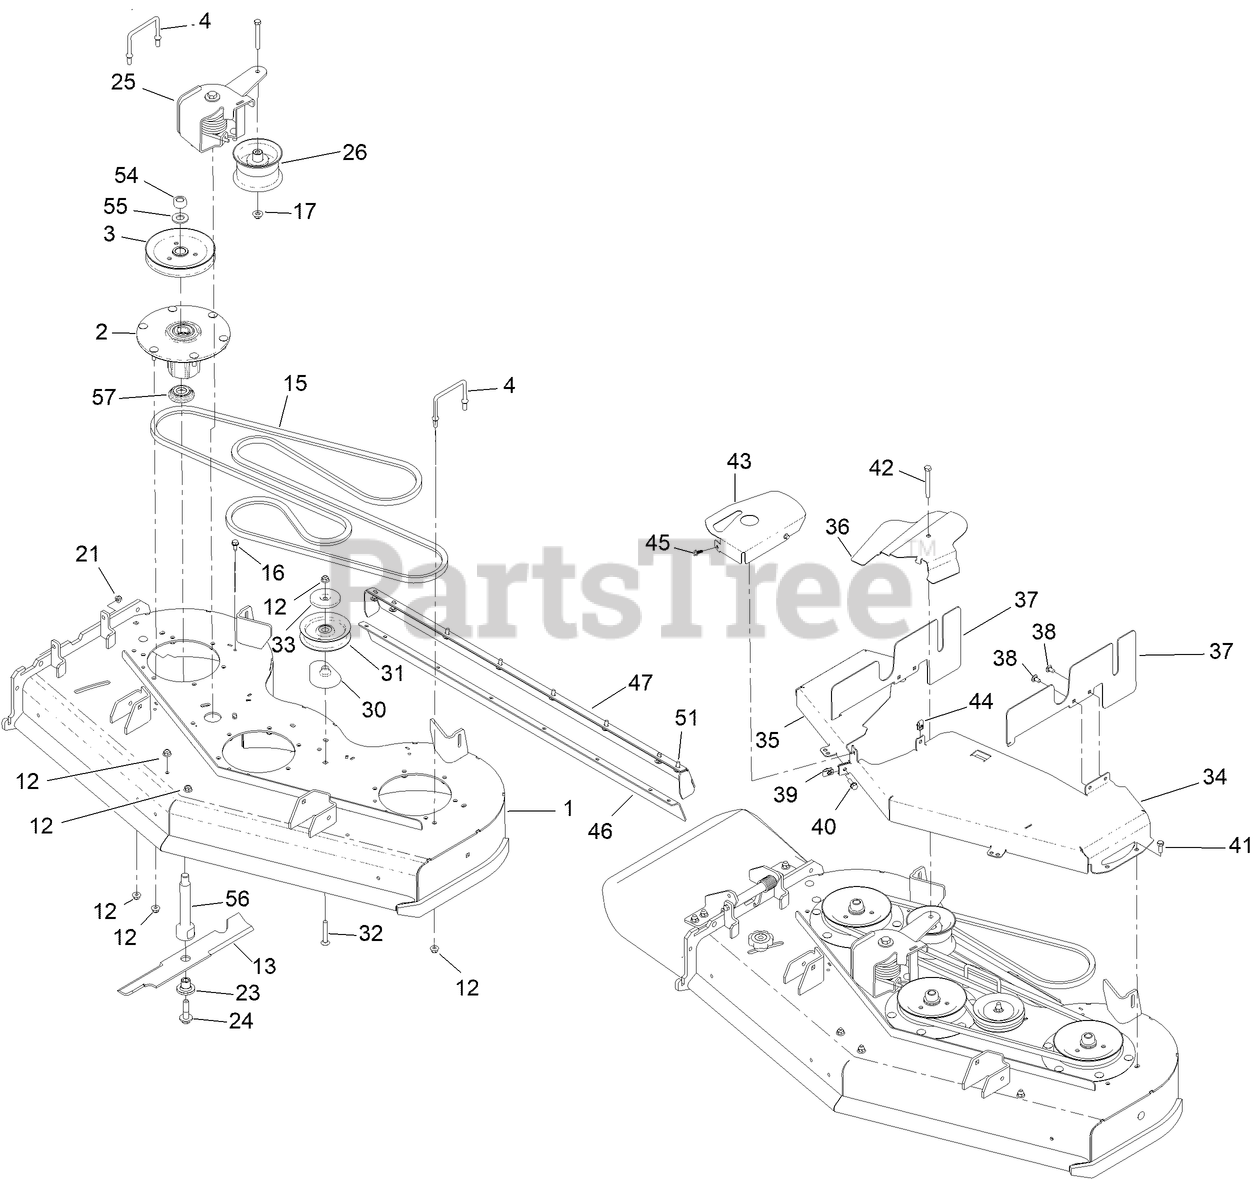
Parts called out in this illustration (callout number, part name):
1	DECK AND DECAL ASM
2	SPINDLE ASM
3	SHEAVE-BLADE, DRIVE
4	WIREFORM-COVER
12	NUT-HF, NI
13	BLADE-16.50 ATOMIC
15	BELT-V
16	SCREW-HWHTF
17	NUT-FLANGE, NI
21	NUT-HF, NI
23	BUSHING-HEX
24	SCREW-SEMS
25	GS TORSION IDLER ASM II
26	PULLEY-IDLER
30	SPACER-PULLEY
31	PULLEY-IDLER, FLAT
32	SCREW-CARR
33	SHIELD-DUST
34	COVER-BELT, LH, CE
35	COVER-BELT, RH CE
36	COVER-IDLER, CE
37	COVER-SIDE, LH (CE)
38	SCREW-CARR
39	NUT-U
40	SCREW-HHF
41	SCREW-HH
42	SCREW-HH
43	COVER-IDLER, CE
45	SCREW-HHF
46	GUARD-RUBBER
47	BRACKET-DEFLECTOR
51	BOLT-CARR
54	NUT-HEX
55	WASHER
56	SHAFT-SPINDLE
57	GUARD-BOTTOM
